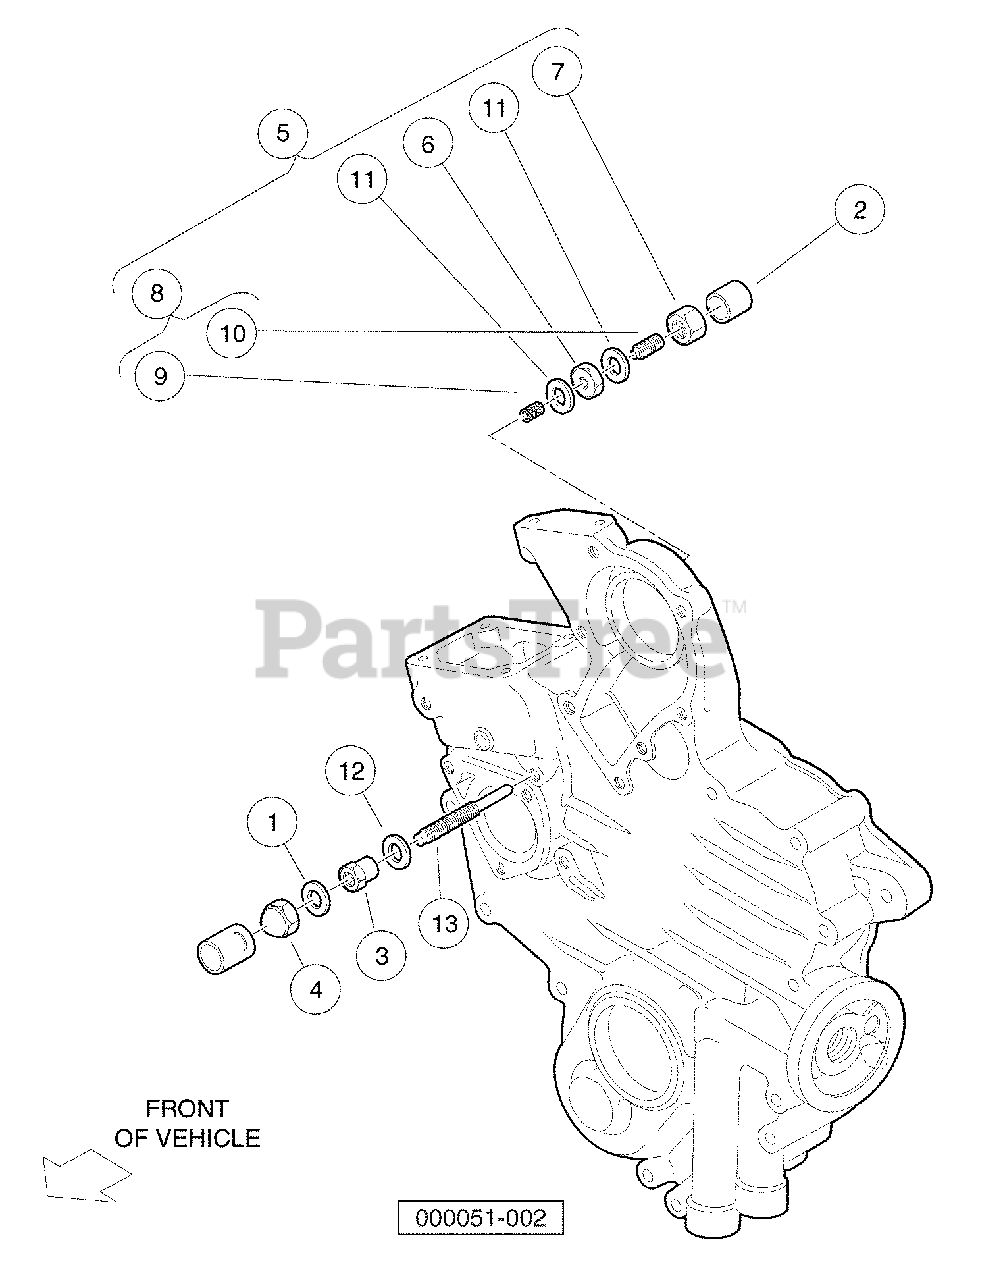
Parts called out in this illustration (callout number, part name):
1	Gasket, 6 X 10
2	Cap, Bolt Assy
3	Nut, Lock, Special
4	Nut, Special
5	Assy, Idle Apparatus
6	Nut, M8, D722 Idle App, Specl
7	Nut, M8, D722 Idle App
8	Assy, Bolt, Adjusting
9	Spring, Idle Apparatus
10	Stud, Idle Adjustment
11	Gasket, Idle Apparatus, Rear
12	Gasket, Idle Apparatus, Front
13	Bolt, Idle Adjusting
